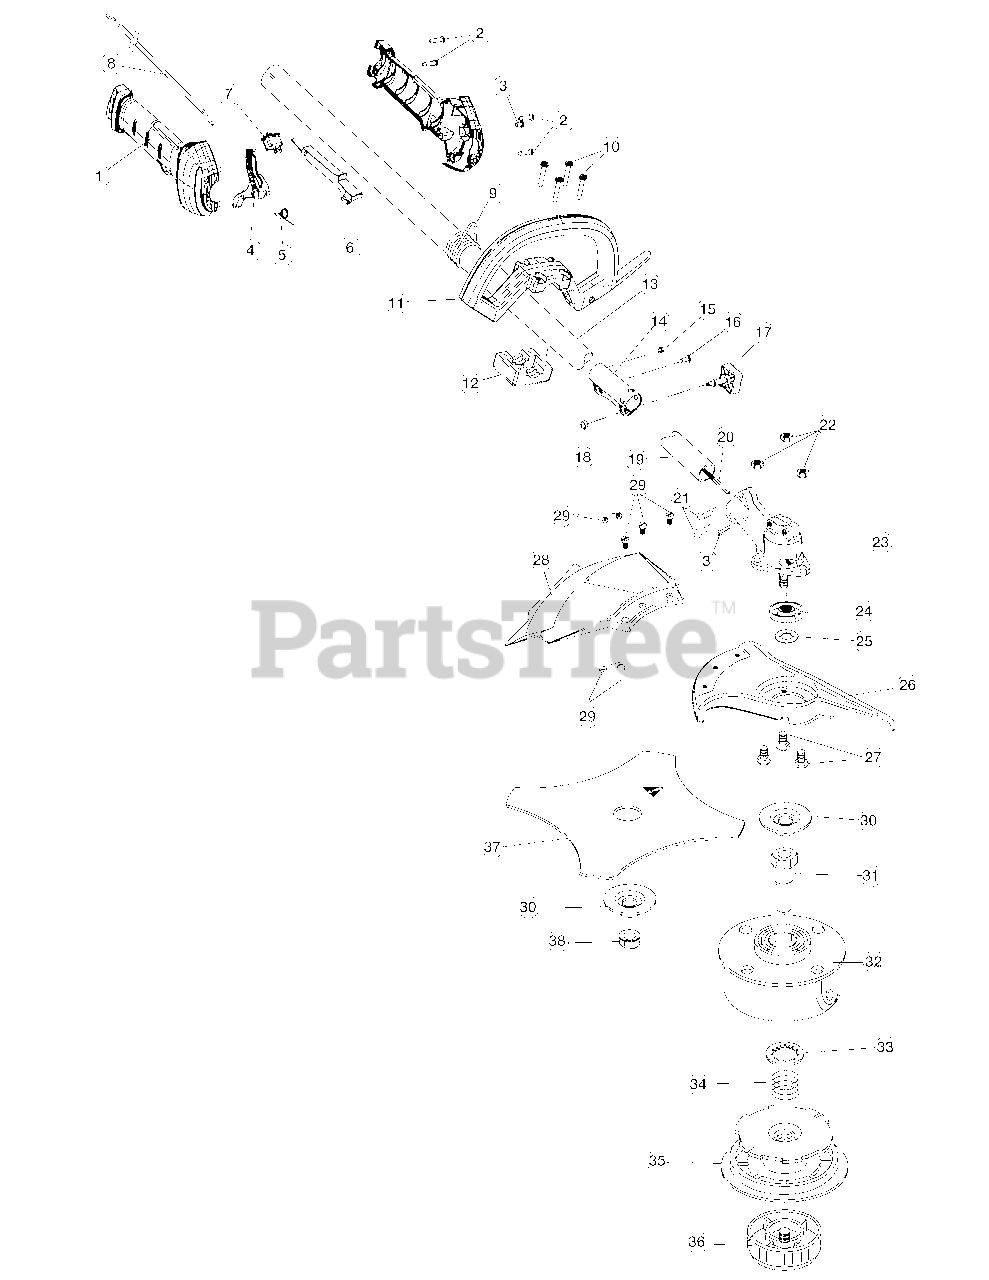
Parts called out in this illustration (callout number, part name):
1	Throttle Grip Assembly (includes 2-7)
2	Screw
3	Anti-Rotation Screw
4	Throttle Trigger
5	Throttle Trigger Spring
6	Lockout
8	Throttle Cable
9	Harness Clip
12	D-Handle Base
13	Upper Drive Shaft Assembly
14	Split Boom Coupler Assembly
17	Knob (includes 18)
18	Nut
19	Lower Drive Shaft Housing Assembly
20	Lower Flex Shaft
21	Gearbox Mounting Hardware
22	Shield Mounting Hardware
23	Gearbox Assembly (includes 3, 21, 26 & 27)
24	Blade Driver
26	Blade Shield/Shield Mount
27	Shield Mounting Screw
28	Shield Assembly (includes 29)
29	Blade Assembly
30	Retaining Washer
31	Spool Shaft
32	Outer Spool Assembly
33	Retainer
36	Bump Head Knob Assembly
37	4-Tooth Blade
38	Nut
